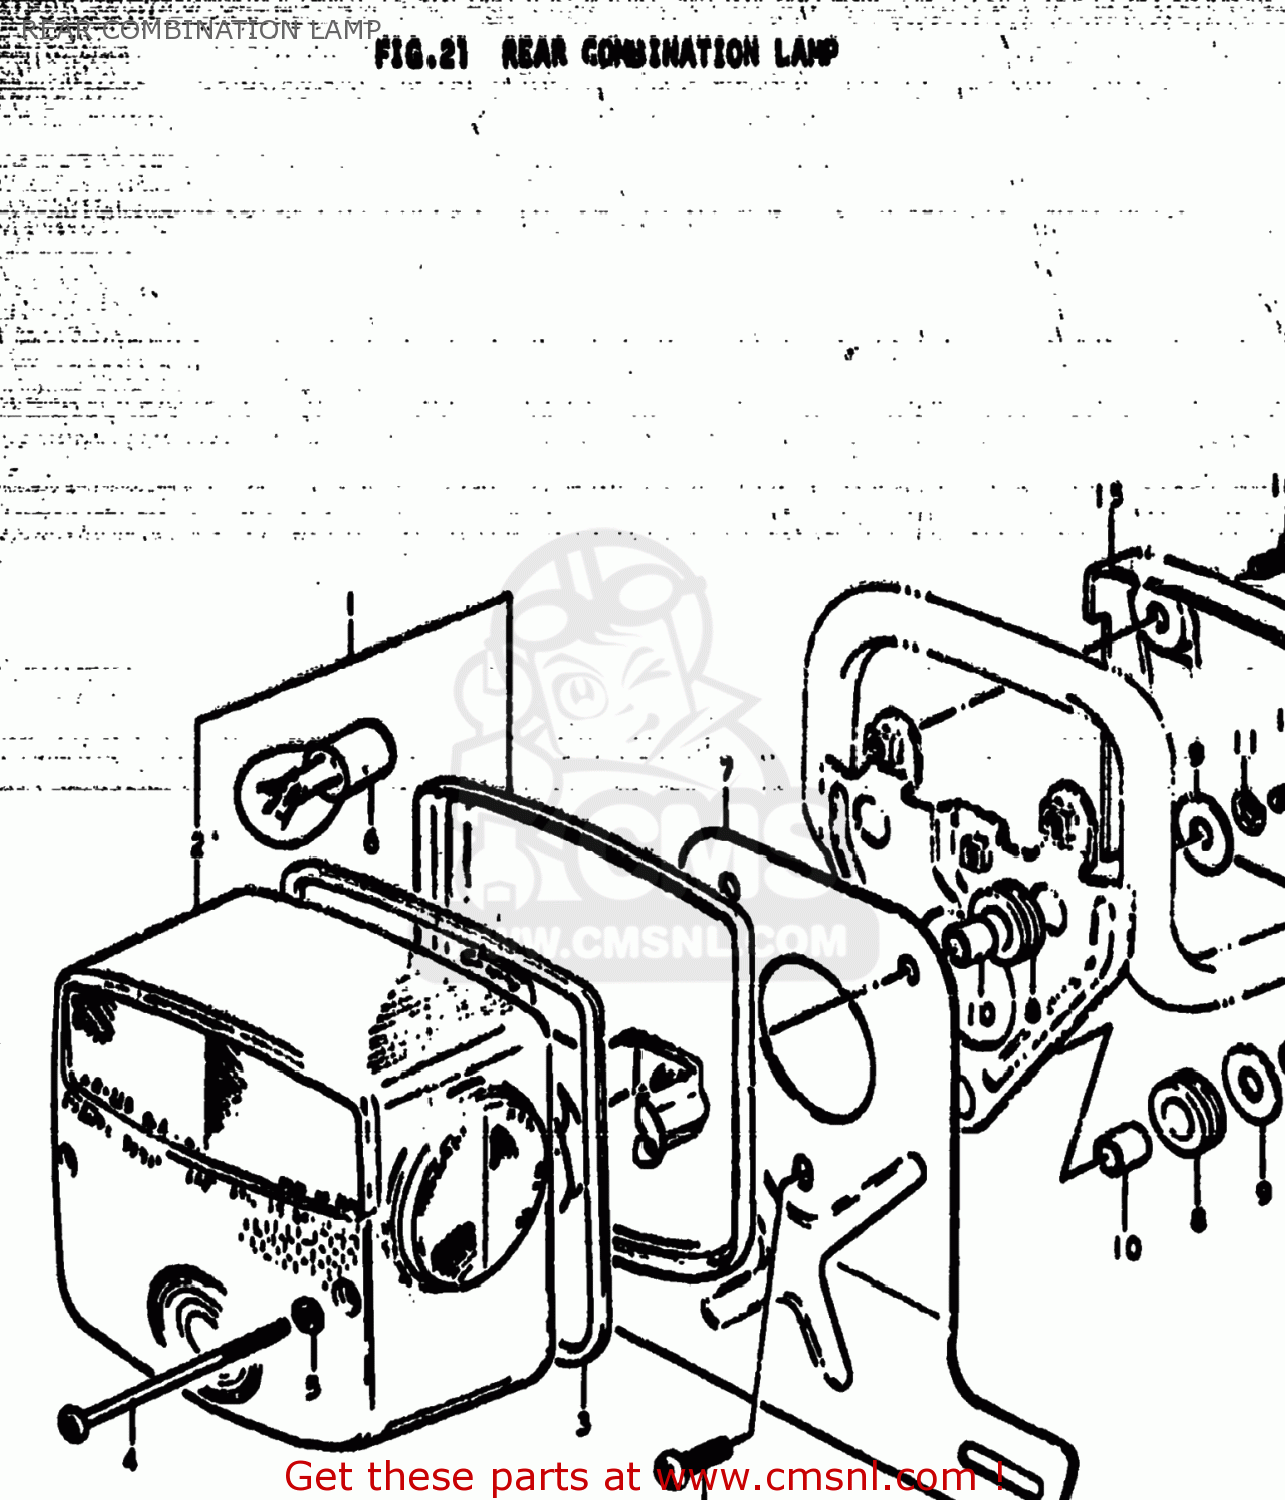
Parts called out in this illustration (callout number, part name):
1	LAMP ASSEMBLY,REAR COMBINATION
2	LENS,REAR COMBINATION LAMP
3	GASKET (NAS)
4	SCREW
5	GASKET (NAS)
6	BULB(6V32/3CP,STANLEY)
7	BRACKET,LICENSE PLATE
8	CUSHION
9	WASHER (6.5X24X1.6)
10	SPACER,REAR COMBINATION LAMP
11	LOCK WASHER
12	BOLT
13	SCREW
14	NUT
15	COVER
16	SCREW 6X12
